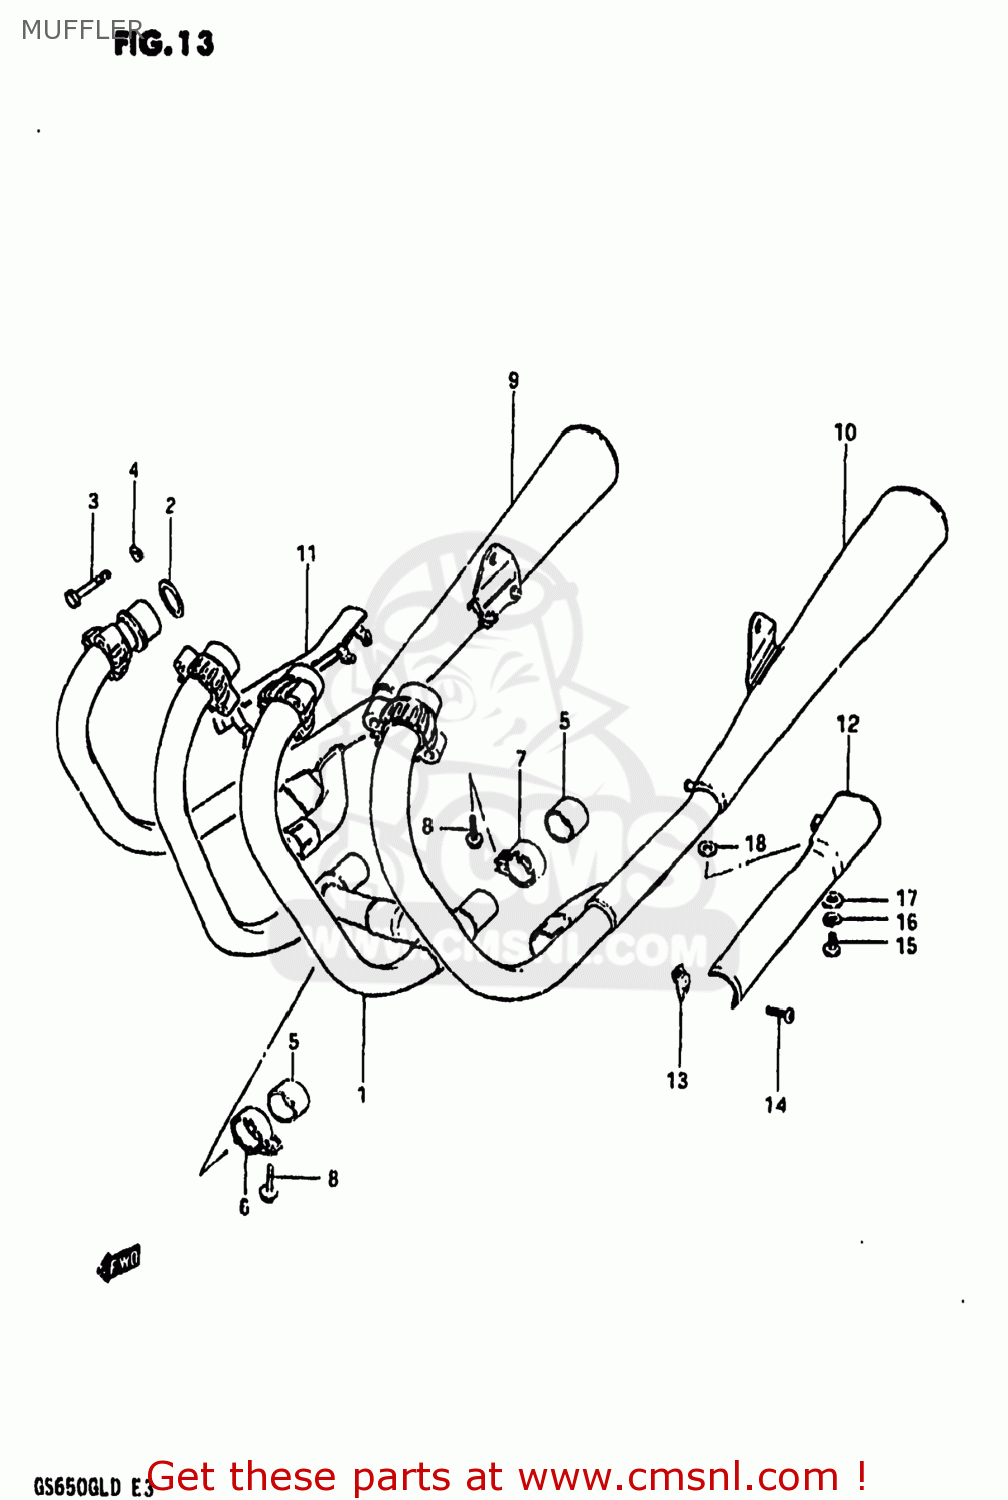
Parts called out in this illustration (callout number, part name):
1	PIPE,EXHAUST CTR
2	GASKET,EXHAUST PIPE (NAS)
3	BOLT 8X40
4	LOCK WASHER
5	CONNECTOR,MUFFLER
6	CLAMP,MUFFLER CONNECTOR,R
7	CLAMP,MUFFLER CONNECTOR,L
8	BOLT
9	MUFFLER ASSEMBLY
10	MUFFLER ASSEMBLY
11	COVER,MUFFLER,RIGHT
12	COVER,MUFFLER,LEFT
13	CLAMP,MUFFLER COVER
14	SCREW 5X20
15	SCREW 6X12
16	LOCK WASHER
17	WASHER
18	GASKET 6.2X12X1.5 (MCA)
